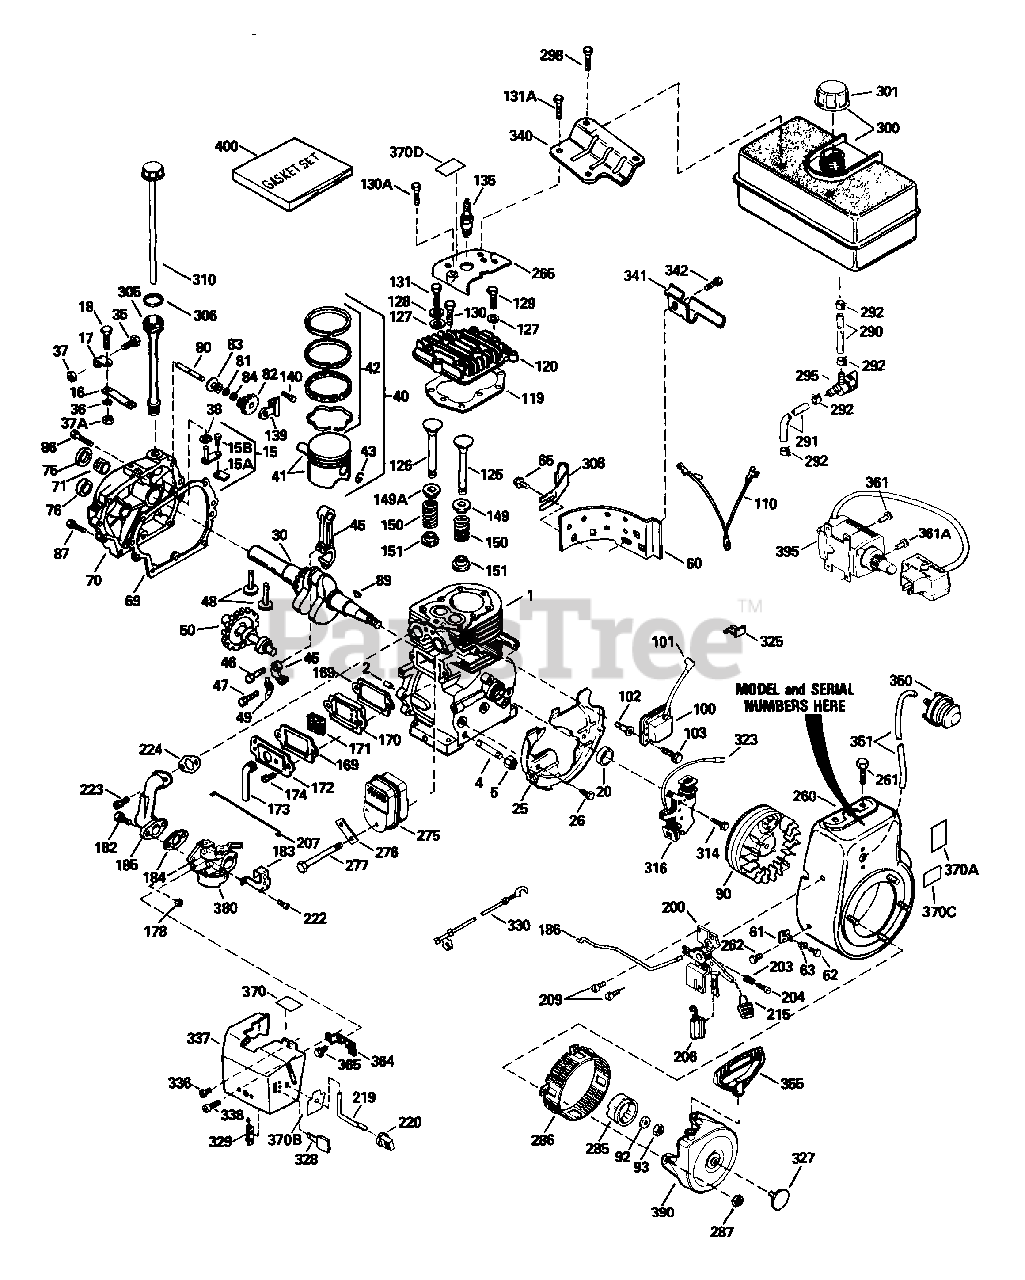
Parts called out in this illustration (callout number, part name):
1	Cylinder
2	Pin, Dowel
4	Nipple, Pipe, 5-1/2"
5	Cap, Oil Drain
15	Rod Ass'y., Governor
15A	Yoke, Governor
15B	Screw, Fil. Hd. Sems, 6-40 x 5/16
16	Lever, Governor
17	Clamp, Governor Lever
18	Screw, Hex Washer Hd., 8-32 x 5/16
20	Seal, Oil
25	Baffle, Blower Housing
26	Screw, Hex Washer Hd. Durlok, 1/4-20 x 5/8
30	Crankshaft
35	Screw, Hex Washer Hd., 10-32 x 3/4
36	Washer, E.T. Lock
37	Nut and Lock Washer 10-32 Keps
37A	Lock Nut, Hex "Keps," 8-32 No. 8
38	Ring Retaining
40	Piston, Pin & Ring Ass'y.
41	Piston & Pin Ass'y.
42	Ring Set, Piston (Std.)
43	Ring, Piston Pin Retaining
45	Rod Ass'y., Connecting
46	Bolt, Connecting Rod
47	Bolt, Connecting Rod
48	Lifter, Valve
49	Dipper, Oil
50	Camshaft (Mechanical Compression Release)
61	Bracket, Grommet Mounting
62	Screw, Pan Hd. Taptite, 8-32 x 3/8
63	Grommet, Plastic
65	Screw, Hex Hd. Sems, 10-24 x 1/2
69	Gasket, Cylinder Cover
70	Cover Ass'y., Cylinder
71	Bushing, Cylinder Cover
75	Seal, Oil
76	Seal, Oil
80	Shaft, Governor
81	Washer, Flat
82	Gear, Governor
83	Spool Governor
84	Ring, Retaining
86	Screw, Hex Washer Hd. Power Lok, 1/4-20 x 1-3/16
87	Screw, Hex Washer Hd. Power Lok, 1/4-20 x 1-11/16
89	Key, Flywheel
90	Flywheel (w/Ring Gear)
92	Washer, Lock
93	Nut, Flywheel
100	Solid State Ass'y.
101	Cover, Spark Plug
102	Stud, Solid State Mounting
103	Screw, T-15 Torx Hex Washer Hd. Sems, 10-24 x 1
110	Wire, Ground
119	Gasket, Cylinder Head
120	Head, Cylinder
125	Valve, Exhaust
126	Valve, Intake
127	Washer, Flat
128	Washer, Belleville
129	Screw, Special Hex Hd. Tapped, 5/16-18 x 1-3/4
130	Screw, Hex Flange Hd., 5/16-18 x 1-1/2
130A	Screw, Hex Washer Hd. Taptite, 1/4-20 x 5/8
131	Screw,
131A	Screw, Hex Hd., 5/16-18 x 5/8
135	Spark Plug
139	Bracket, Governor Gear
140	Screw, Hex Washer Hd. Thread Forming, 10-24 x 1/2
149	Cap, Upper Valve Spring
149A	Seal Ass'y., Intake Valve
150	Spring, Valve
151	Cap, Lower Valve Spring
169	Gasket, Breather
170	Body, Breather
171	Element, Breather
172	Cover, Breather
173	Tube, Breather
174	Screw, Hex. Hd., Sems, 10-24 x 1/2
178	Nut 8 Lock Washer, 1/4-28
182	Screw, Fil. Hd. Sems, 1/4-28 x 1
183	Bracket, Choke
184	Gasket, Intake Pipe
185	Pipe, Intake
186	Link, Governor
200	Bracket Ass'y., Control
203	Spring, Compression
204	Screw, Fil. Hd., 5-40 x 7/16
207	Link, Governor-to-Throttle
209	Screw, Hex Washer Hd. Thread Cutting, 10-32 x 1/2
215	Knob, Control
219	Rod, Choke
220	Knob, Choke
222	Screw, Fil. Hd. Sems, 10-32 x 1/2
223	Screw, T-30 Torx Fil. Hd. Sems, 5/16-18 x 1-1/8
224	Gasket, Carburetor
260	Housing, Blower
261	Screw, Hex Hd. Spin Lock Thread Forming, 5/16-18 x 3/4
262	Screw,
265	Cover, Cylinder Head
276	Plate, Lock
277	Screw, Flanged Hex Hd., 5/16-18 x 4-3/16
285	Hub, Starter
286	Screen, Starter
287	Nut & Lock Washer, 1/4-28
290	Line, Fuel (8-1/4")
291	Line, Fuel (16")
292	Clamp, Fuel Line
295	Valve, Fuel Shut-Off
298	Screw, Hex Washer Hd. Thread Cutting, 1/4-15 x 7/8
300	Tank, Fuel
301	Cap, Fuel Tank
305	Tube, Oil Fill
308	Clip, Fill Tube
310	Dipstick, Oil
314	Screw, Hex Hd. Sems, 1/4-20 x 3/4
316	Coil Ass'y., Alternator (18 Watt)
325	Clip, Spring
327	Plug, Starter
328	Key Ignition
330	Wire, Ground
336	Screw, Hex Washer Hd. Self-Drilling, 10-32 x 1/2
337	Cover, Carburetor
338	Screw, Hex Washer Hd. Sems, 10-32 x 3/8
340	Bracket, Fuel Tank
341	Plate, Fuel Tank Mounting
342	Screw, Hex Washer Hd. Durlok, 1/4-20 x 5/8
350	Primer Ass'y.
351	Line, Primer
355	Starter Handle, Mitten Grip
361	Screw, Hex Hd. Shoulder, 1/4-20 x 1/2
361A	Screw, Torx T-30 Hex Hd. Sems, 1/4-20 x 1/2
364	Bracket, Carburetor Cover Mounting
365	Screw, Hex Washer Hd. Sems, Taptite, 8-32 x 27/64
370	Decal, Warning (Bilingual)
370A	Decal, Name
370B	Decal, Control
370C	Decal, Primer
370D	Decal, Instruction
380	Carburetor
390	Starter, Rewind
395	Motor Kit, Electric Starter (120 Volt)
400	Gasket Set
